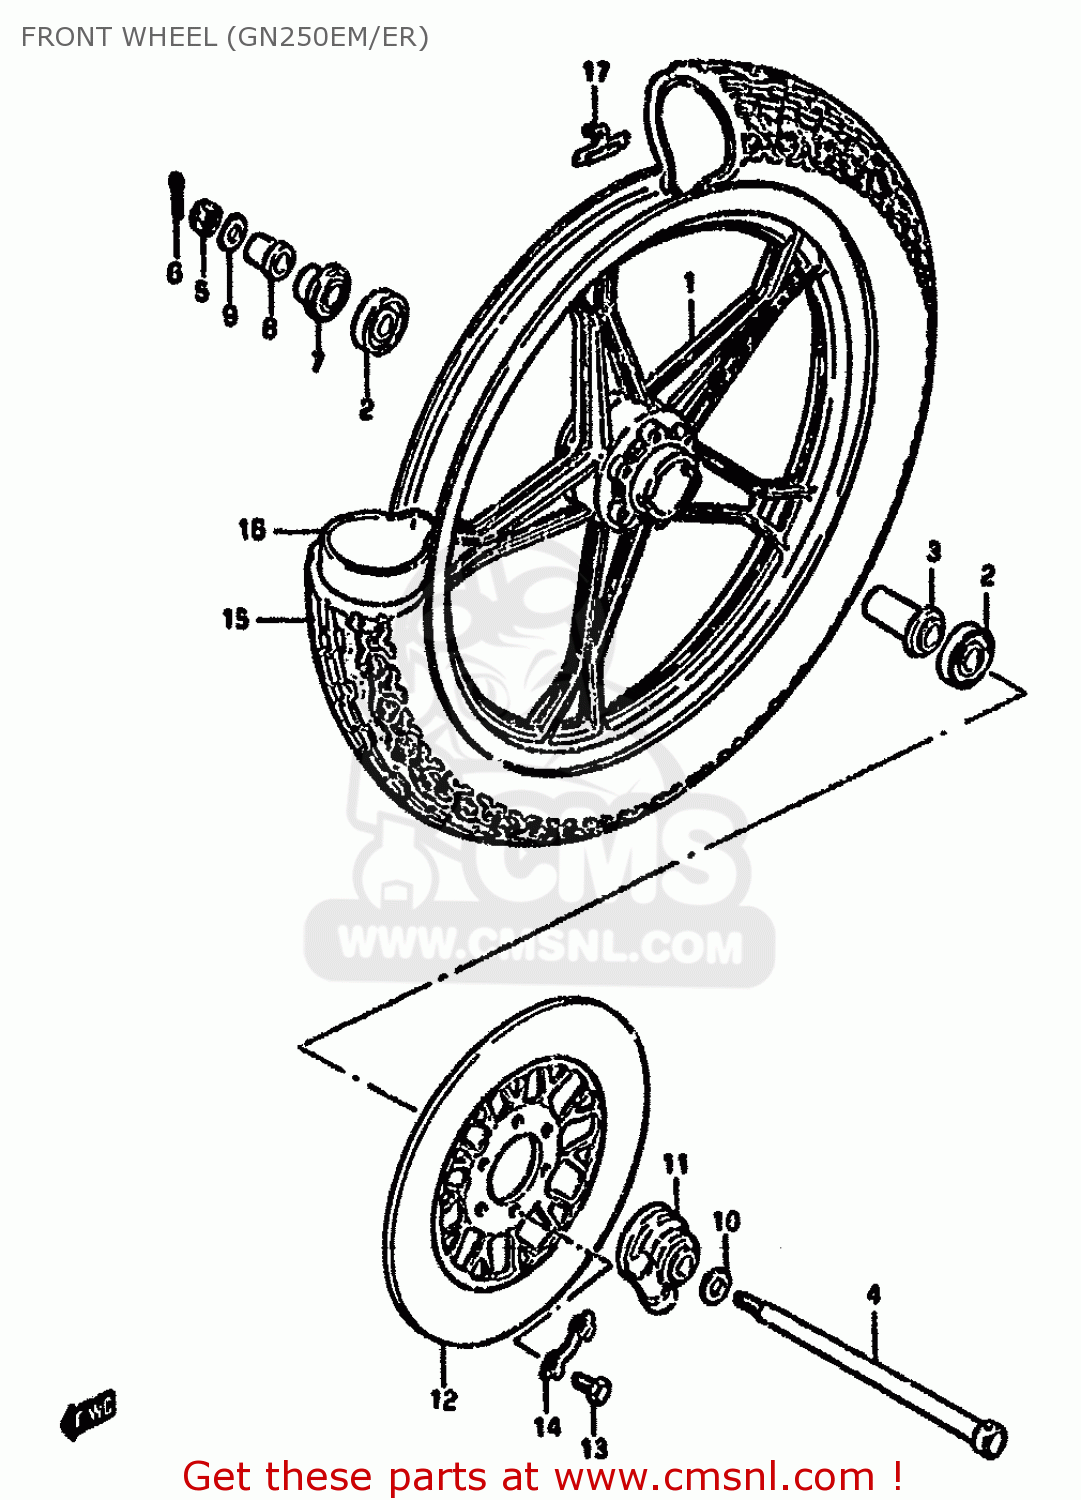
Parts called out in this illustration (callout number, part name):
1	WHEEL,FRONT (1.60X18)
2	BEARING
3	SPACER,FR HUB BEARING
4	AXLE,FR
5	NUT 12MM
6	COTTER PIN
7	SPACER,FR AXLE,R
8	SPACER
9	WASHER
10	WASHER(15.5X26X2.3)
11	BOX ASSY,SPEEDOMETER GEAR
12	DISC,FR BRAKE
13	BOLT(8X25)
14	WASHER
15	TIRE,FRONT
16	TUBE,INNER
17	BALANCER,WHEEL
20	RIM,FR WHEEL
21	SPOKE ASSY,FR WHEEL
22	BALANCER,WHEEL (B)
